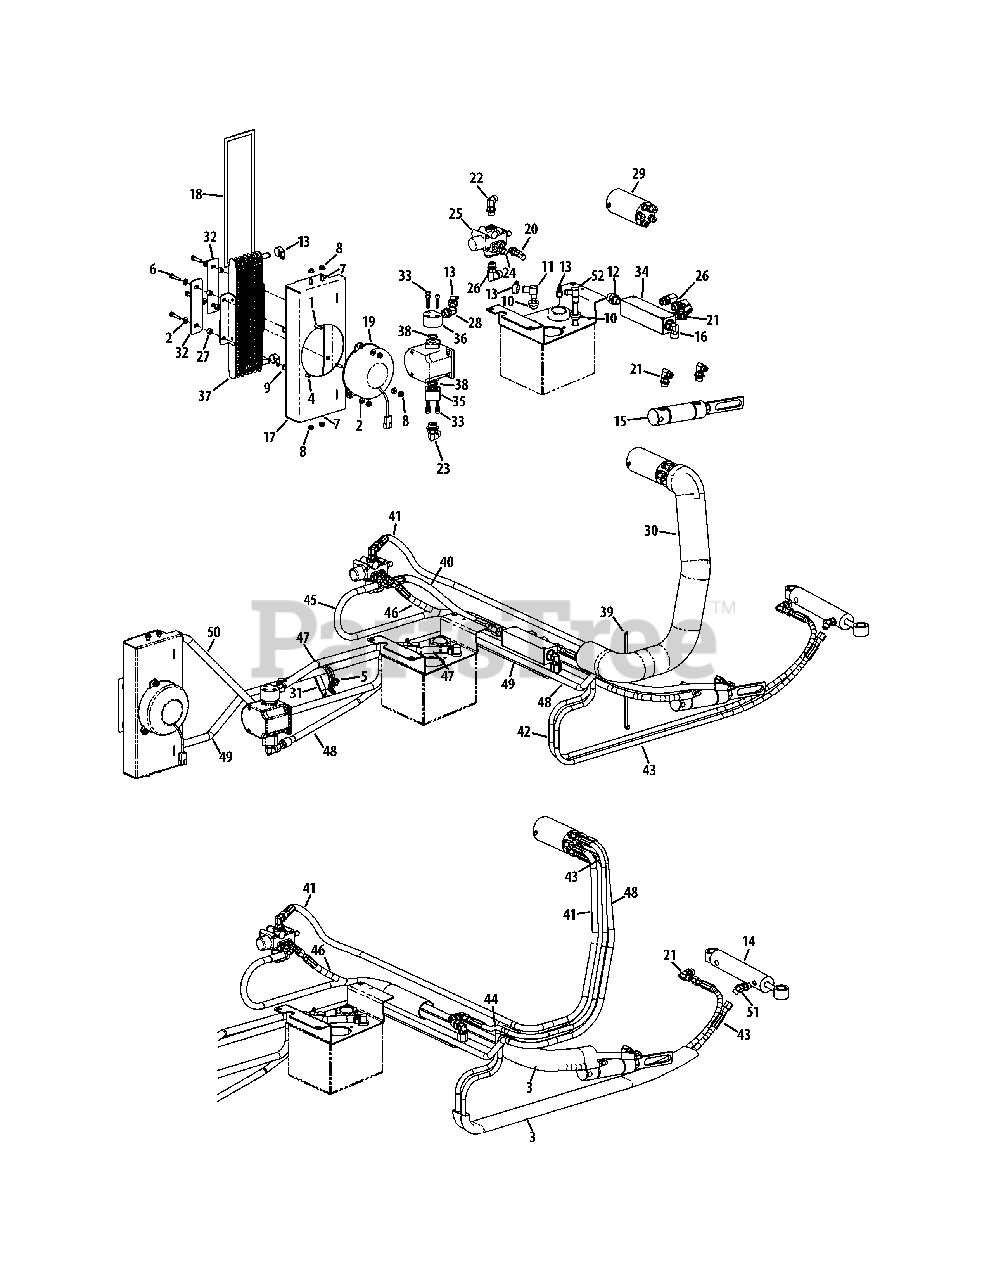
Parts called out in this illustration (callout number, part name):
1	Hex Screw, 1/4-20 x 1.00
2	Washer, .281 x .625 x .063
4	Hex Screw, 1/4-20 x .620
5	Hex Flange Screw, 1/4-20 x .500
6	Hex Screw, 1/4-20 x 1.25
7	Carriage Bolt, 1/4-20 x .620
8	Flange Top Lock Nut, 1/4-20
9	Nut, 1/4-20
10	Grommet, .54 x .78
11	Elbow Fitting, 5/8 x 1/2
12	Hydro Adapter
13	Hose Clamp
14	Steering Cylinder
15	Hydro Cylinder, 1.50 x 2.75
16	Hydro Adapter
17	Radiator Housing Assembly
18	Heat Exchanger Screen
20	Elbow Fitting, 40RB-40RS
21	Elbow Fitting, 40RS-60RB
22	Elbow Fitting, 60RB-60RS
23	Elbow Fitting, 60RS-80RB
24	Elbow Fitting, 40RB-40RS
25	Dual Action Lift Hydro Valve
26	Elbow Fitting, 80RS-60RB
27	Spacer, .256 x .500 x .330
28	45° Fitting, 3/4 x 1/2
29	Hydro Steering Valve
30	Anti-Abrasion Sleeve
31	Loop Clamp, 2.00 x 3.50
32	Hydro Cooler Screen Retainer Brkt.
33	Socket Head Screw, 6-1.0
34	Hydro Manifold, 08 x 06
35	Pump Adapter Fitting Mount
36	Suction Hydro Fitting, 3/4-16
37	Oil Radiator
38	O-Ring, .734 x .139
39	Cable Tie
40	Lift Valve to Manifold Hose Assy.
41	Lift Valve to Steering Valve Assy.
42	Steering Ext. to Steering Valve Hose Assy.
43	Steering Ret. to Steering Valve Hose Assy.
44	Manifold to Steering Valve Hose Assy.
45	Cylinder Ret. to Lift Valve Hose Assy.
46	Cylinder Ext. to Lift Valve Hose Assy.
47	Tank to Pump Hose Assembly
48	Pump to Steering Valve Hose Assy.
49	Manifold to Exchanger Hose Assy.
50	Exchanger to Tank Hose Assy.
51	45degree Elbow Fitting
52	Elbow, 1/2 x 5/8 Barb w/ Straw
